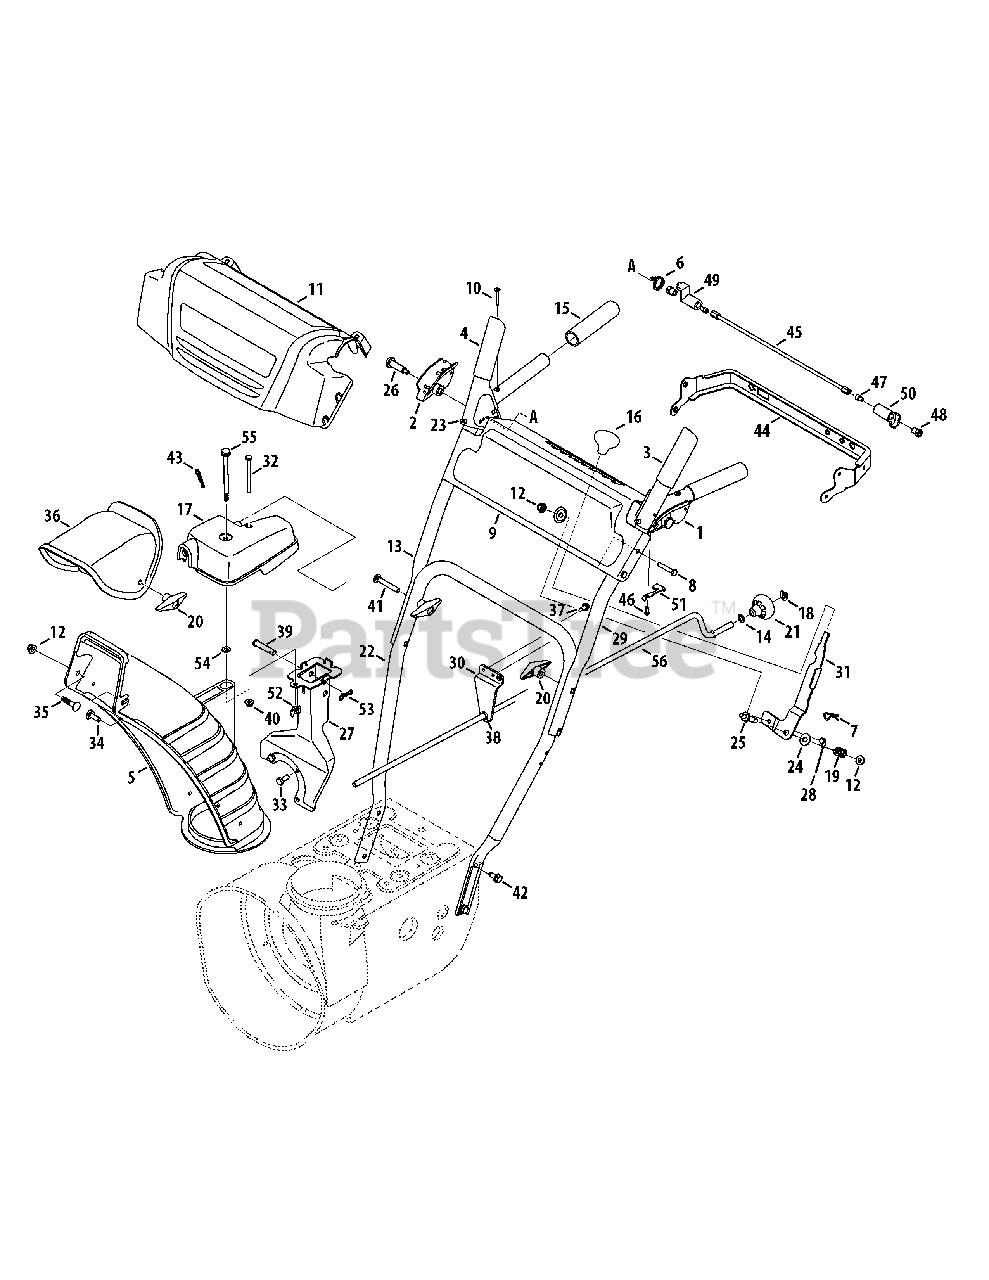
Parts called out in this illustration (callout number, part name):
1	Handle Assembly, Clutch Lock, LH
2	Handle Assembly, Clutch Lock, RH
3	Handle Ass’y, Engage, LH
4	Handle Ass’y, Engage, RH
5	Chute, Lower
6	Spring, Torsion, .8156 ID x .3038
7	Click Pin
8	Screw, 1/4-20 x 1.625
9	Panel, Handle, (no cutout)
10	Screw, Machine, #10-24, 1.375
11	Handle Panel Cover
12	Nut, Flange Lock, 5/16-18, Nylon
13	Handle, Upper, RH
14	Washer, Flat, .375 x .738 x .063
15	Grip, 1.0 ID x 5.0
16	Knob, Shift, Black
17	Gearbox Assembly
18	Cap, Push, 3/8 Rod
19	Spring, .39 x .60 x .88
20	Knob, 5/16-18, Black
21	Crank Knob
22	Handle, Lower
23	Bumper, Rubber, .62 OD x .22
24	Washer, Flat, .385 x .870 x .092
25	Bolt, Shoulder, 5/16-18 x 0.905
26	Screw, Shoulder, .43 x 1.3, 1/4-20
27	Bracket, Chute Support
28	Cable, Speed Selector
29	Handle, Upper, LH
30	Bracket, Rod
31	Shift Lever
32	Screw, 1/4-20 x 3.00
33	Screw, 5/16-24 x .750
34	Bolt, Carriage, 5/16-18, 1.0
35	Bolt, Carriage, 5/16-18, .750
36	Chute, Upper, w/ Label
37	Screw, 1/4-20 x .625
38	Bushing, Plastic, .380
39	Pin, Clevis
40	Nut, Flange Lock, 1/4-20
41	Screw, Carriage, 5/16-18, 2.25
42	Screw, 5/16-18, 2.25, Gr5
43	Pin, Cotter
44	Bracket, Panel
45	Rod, Pivot
46	Screw, #8-16 x .50
47	Screw, 1/4-20 x .50
48	Nut, Hex, 1/4-20
49	Plate, Lock
50	Cam, Clutch Lock
51	Spring, Clutch Lock
52	Nut, Wing
53	Bow-Tie Cotter Pin
54	Washer, Flat, .25 x .630 x .0515
55	Scr. Shldr. Flg., .312 x 3.5 x 1/4-20
56	Crank, Chute
